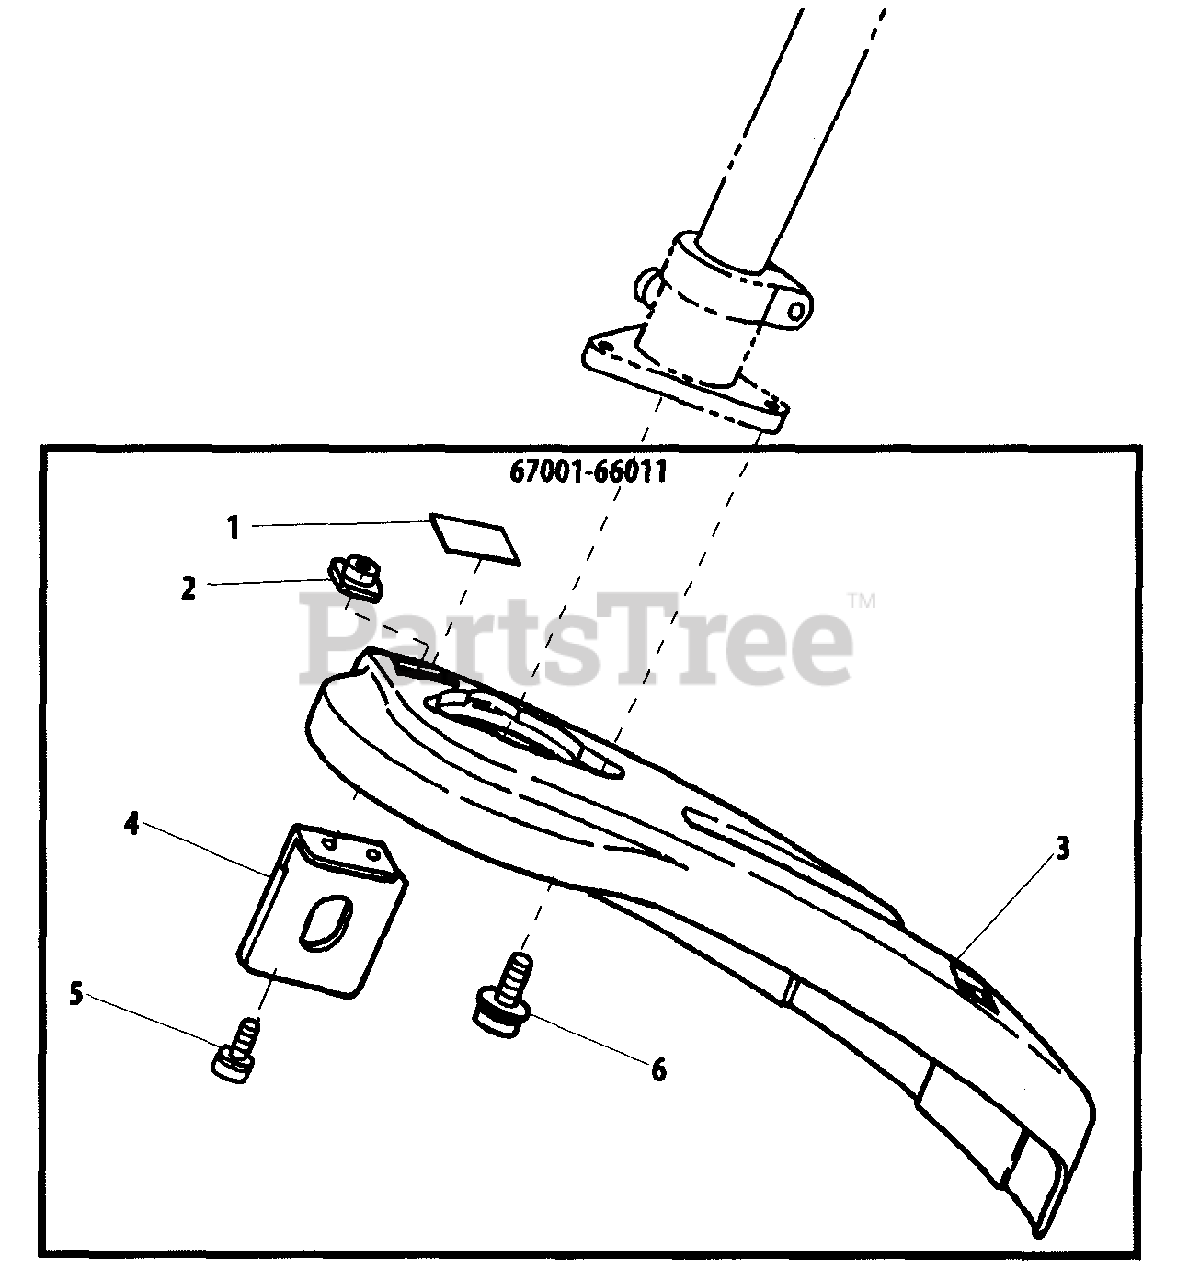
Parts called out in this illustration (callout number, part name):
1	LABEL - CAUTION
2	NUT - NYLON
3	GUARD
4	KNIFE, TRIMMER LINE
5	SCREW - 4X16
6	SCREW - 5X16
67001-66011	DEBRIS SHIELD KIT
